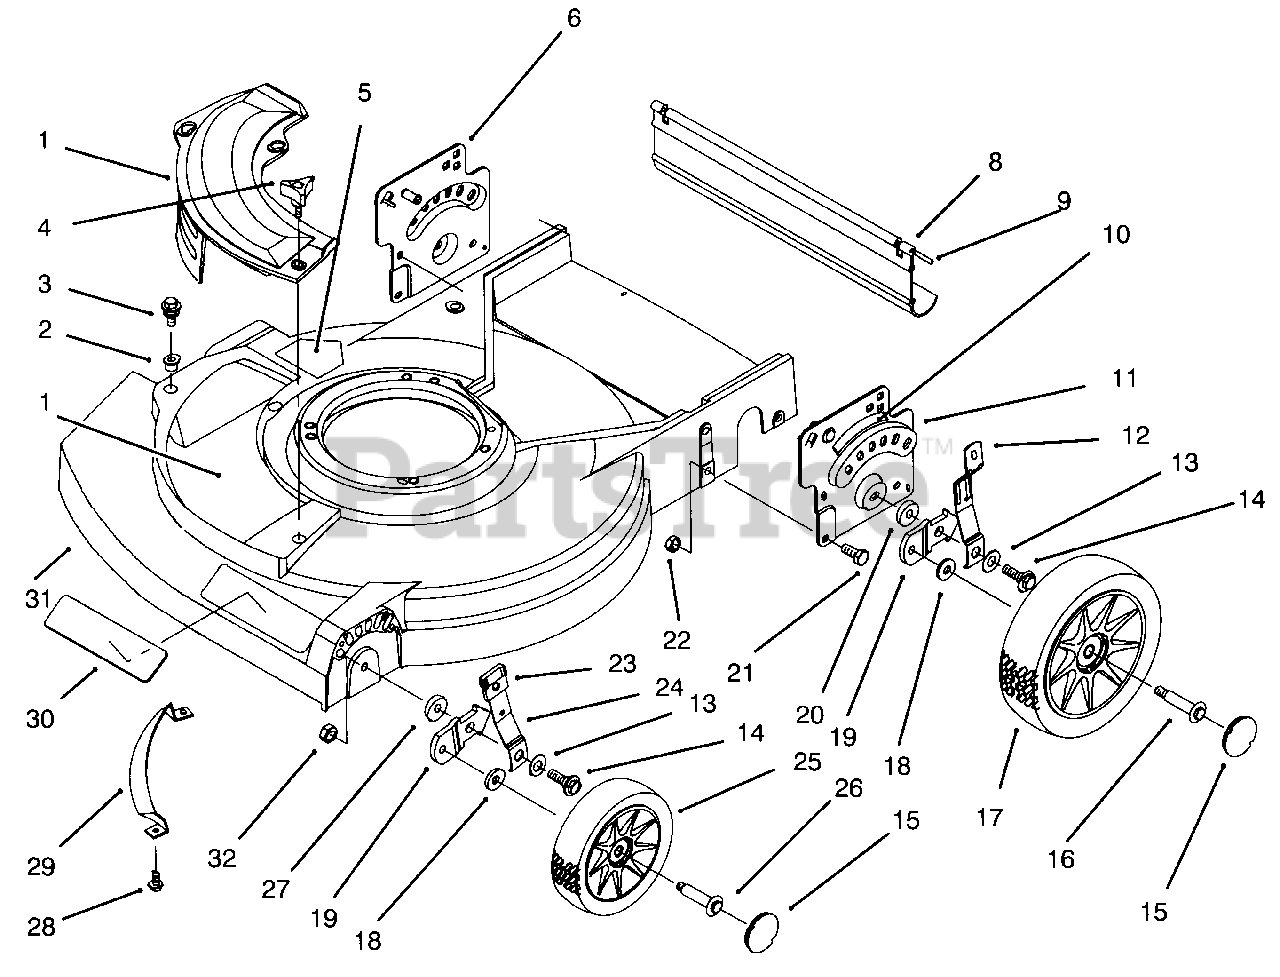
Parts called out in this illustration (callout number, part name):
1	Cover-Plate, Mulch
2	Grommet
3	Screw-Thread Forming
4	Knob
5	Decal-Danger (English)
6	Bracket-Handle, R.H.
8	Shield-Trailing
10	Decal-H.O.C. L.H.
11	Bracket-Handle
12	Spring Arm Assembly
13	Washer-Belleville
14	Bolt-Shoulder
16	Bolt-Wheel
17	Wheel Assembly 8"
18	Washer-Wheel Bolt
19	Bracket-H.O.C.
21	Screw
22	Nut-Lock
23	Knob-Spring Arm
24	Spring Arm Assembly
25	Wheel-6"
26	Bolt-Wheel
29	Bar-Toe
30	Applique
31	Housing-21" (Incl. Ref. #5 & 30)
32	Nut-Lock
